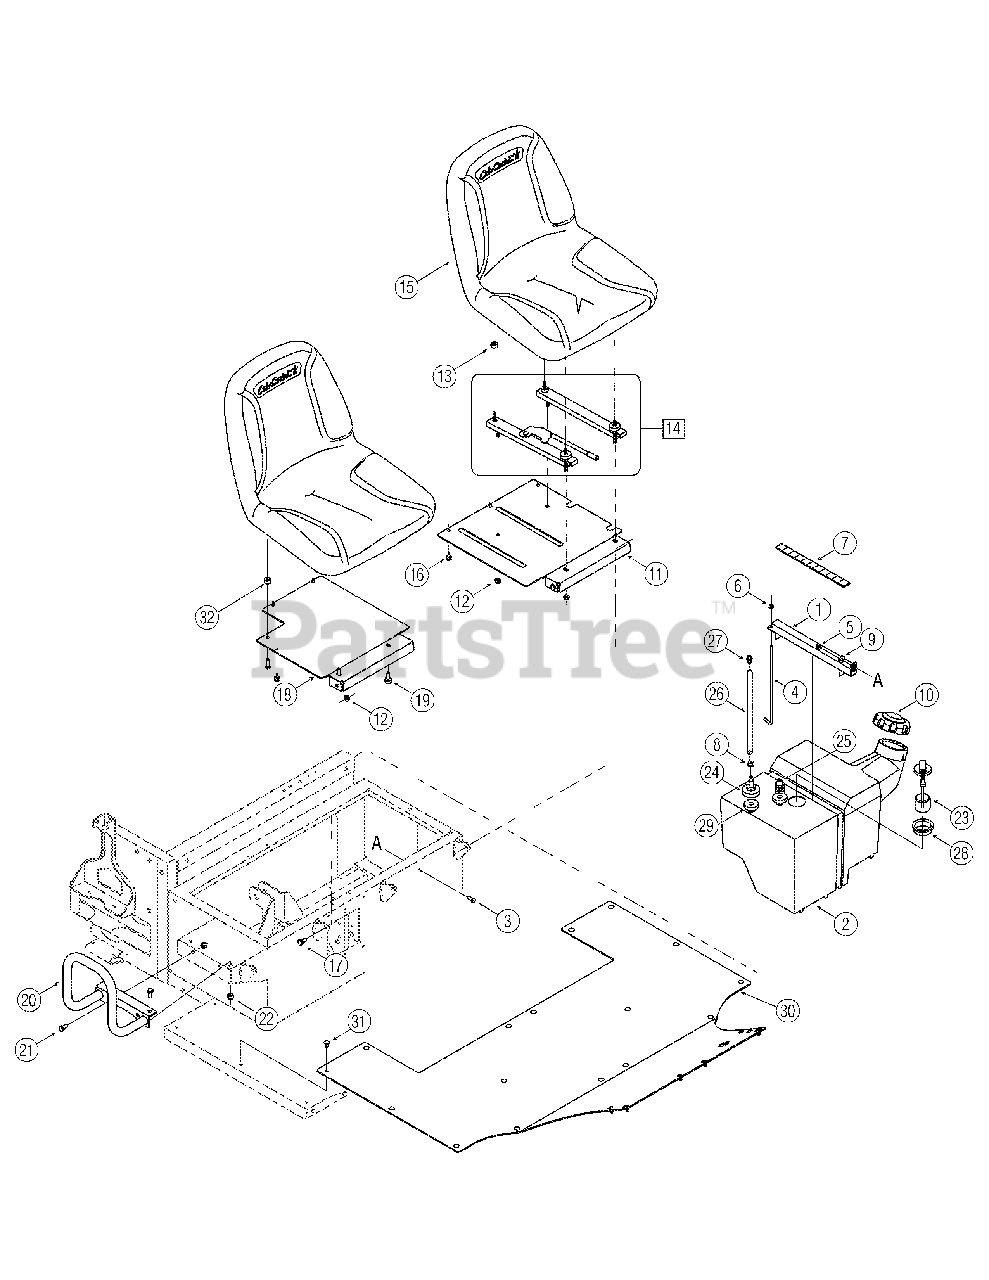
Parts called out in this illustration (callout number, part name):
1	Bracket Assembly, Fuel Tank
2	Tank Assembly, Fuel
3	Hex Screw, 5/16-18 x .75
4	Hold-down Rod, Fuel Tank
5	Sems Nut, 5/16-18
6	Nut, Flange Lock, 1/4-20
7	Gasket, Fuel Tank (11")
8	Clamp, Hose
9	Washer, .349 x .879 x .063
10	Cap, Fuel
11	Plate, Seat, LH
12	Nut, Flange Lock, 5/16-18, Gr5
13	Spacer, Seat
14	Track Assembly, Seat
15	Seat
16	Bumper
17	Shoulder Screw,.435 x.178-5/16 x.56
18	Plate, Seat, RH
19	Hex Screw, 5/16-18 x 1.0
22	Nut, Hex Lock Nylon, 3/8-16
23	Low Fuel Sensor
24	Fuel Return Fitting
25	Fuel Tank Shut Off Valve
26	Fuel Line Hose 20-inch
29	Fuel Tank Grommet
30	Floor Mat
31	Retainer Clip
32	Spacer, .315 x .75 x .375
